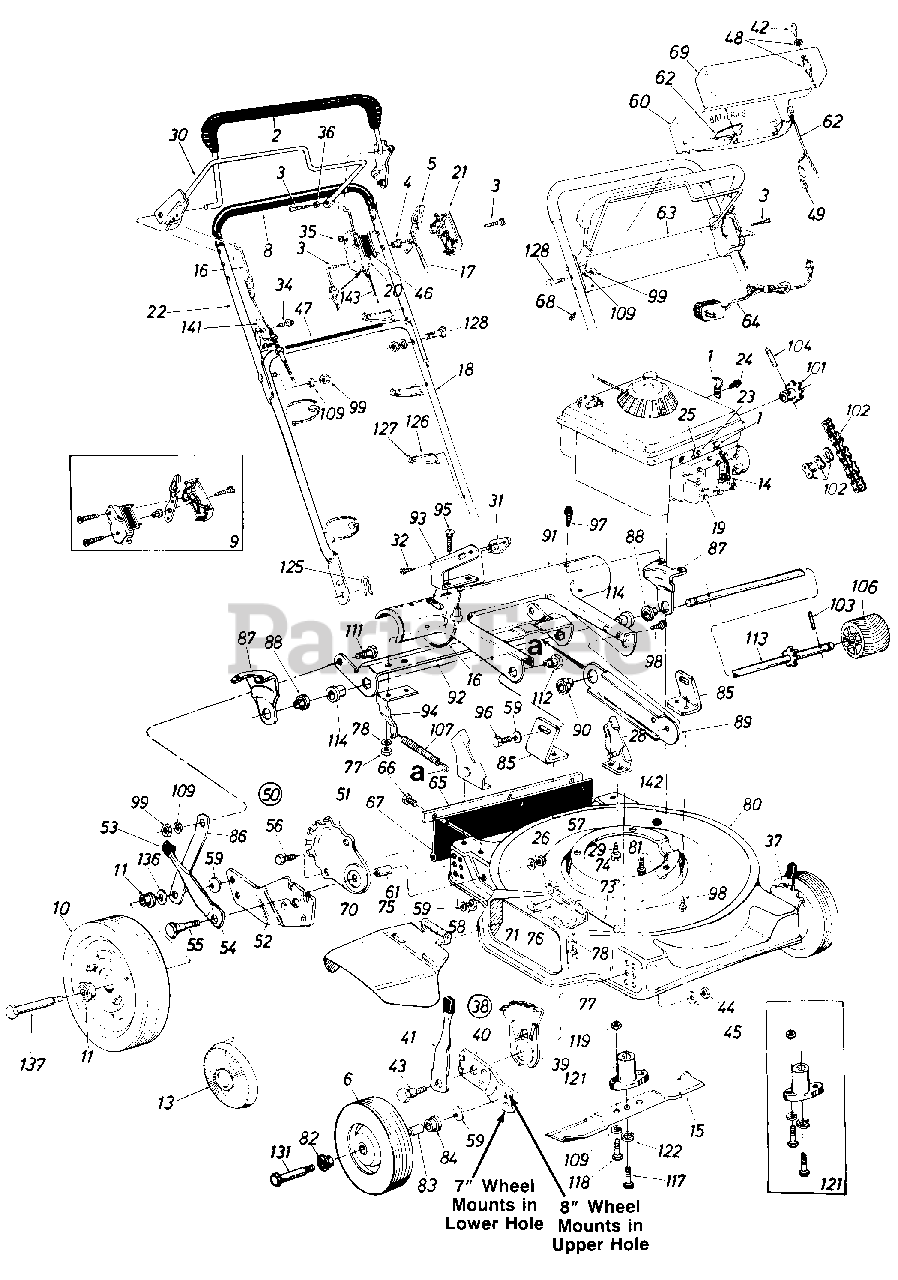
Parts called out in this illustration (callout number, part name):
1	Casing Clamp
2	Control Handle Ass'y.-L.H.
3	Truss Mach. Hi-B Tap Scr. #12 x 1.5"
4	Control Disc Pin
5	Throttle Control Lever
6	Front Wheel Ass'y. Comp.
9	Control Housing Comp.
10	Rear Wheel Ass'y. Comp.
11	Fl. Ball Brg. 1/2" I.D.
13	Hub Cap
14	Spark Plug Insulator
15	22" Blade
16	Clutch Cable w/Spring-33"
17	Throttle Wire-53"
18	Lower Handle (Chrome)
19	Engine
20	Clutch Panel Half
21	Control Panel Half
22	Upper Handle (Chrome)
23	Hex B-Tap Scr. #10 x .62"
24	Hex B-Tap Scr. #10 x .38"
25	Casing Clamp
26	Bell-Wash. 5/16" I.D.
28	Handle Brkt. Ass'y-L.H.
29	Hex B-Tap Scr. 5/16-18 x .5"
30	S.P. Bail Ass'y.
31	Barrel Cable Hold-Down R.H.
32	B-Tap Scr. #10 x .38 Lg.
34	Hex Wash. AB-Tap Scr. 5/16 x .75"
35	Spr-Wash. .206 I.D. x .448
36	Spacer .23 I.D. x .30 O.D.
37	Front Height Adj. Ass'y.-L.H.
38	Front Height Adj. Ass'y.-R.H.
39	Height Adj. Plate
40	Pivot Bar
41	Spring Lever Ass'y. w/Knob
42	Ignition Key
43	Shld. Bolt .50 Dia. x .430
44	Hex Nut 3/8-16 Thd.
45	Bell-Wash. .39 I.D. x 1.38 O.D
46	Control Label
47	Instruction Label
48	Ignition Switch
49	Plug
50	Rear Height Adj. Ass'y.-R.H.
51	Index Plate
52	Pivot Bar-R.H.
53	Spring Lever Knob
54	Spring Lever
55	Shld. Bolt .50 Dia. x .433
56	Hex Bolt 3/8-16 x .75
57	Hex Cent. L-Nut /16-18 Thd.
58	Hex Nut 3/8-16 Thd.*
59	Bell-Wash. .40 I.D. x .88 O.D.
60	Battery Pack
61	Spacer .383 I.D. x .503 O.D.
62	Wire Harness
63	Lower Battery Tray
64	Battery Charger
65	Retaining Strip
66	Hex AB-Tap Scr. 1/4 x .62
67	Rear Flap Ass'y.
68	Truss Mach. Hi-Riser Tap Scr. 1" Lg.
69	Battery Tray
70	Chute Deflector Ass'y.
71	Adapter Plate
73	Pivot Pin
74	Push Nut 1/4"
75	Torsion Spring
76	Hex Bolt 1/4-20 x .50 Lg.
77	Hex Nut 1/4-20 Thd.
78	L-Wash. 1/4 I.D.
80	22" Deck Ass'y.
81	Hex TT-Tap Scr. 3/8-16 x 1.0
82	Ball Bearing 3/8" I.D.
83	Spacer
84	Ball Bearing 1/2" I.D.
85	Pivot Brkt.
86	Link
87	Axle Brkt.
88	IFI. Ball Brg. 1/2" I.D.
89	Brg. Support
90	IFI. Ball Brg. 1/2" I.D.
91	Pinion-PivotCover
92	Drive Engagement Cam
93	Engagement Arm-L.H.
94	Spring Bracket
95	Carriage Bolt 1/4-20 x .62
96	Hex Bolt 3/8-16 x .50 Lg.*
97	Hex AB-Tap Scr. 1/4 x .62
98	Hex AB-Tap 1/4 x .62"
99	Hex Nut 5/16-18 Thd.
101	1OT Sprocket Ass'y.
102	#48 Chain 1/2" Pitch 50 Links
103	Spring Pin Spir. 3/16 Dia. x 1 25
104	Spring Pin Spir. 3/16 Dia. x 1.0
106	Drive Pinion
107	Extension Spring 4.25 Lg.
109	L-Wash. 5/16 I.D.
111	Shld. Bolt .437 Dia. x .162
112	Shld. Nut .625 Dia. x .165
113	Pinion Shaft w/7T Sprocket
114	Fl. Ball Brg. .501 I.D.
117	Hex Bolt 3/8-24 x 2.25
118	Hex Bolt 5/16-24 x 1.0-Spec.
119	Hex Nut 5/16-24 Thd.
121	Blade Adapter Kit
122	L-Wash. 3/8 I.D.-H.D.
125	Intern. Cot. Pin 5/16 Dia.
126	Cable Tie
127	Cable Anchor
128	Curved Carriage Bolt 5/16-18 x 1.38" Lg.
131	Front Axle Bolt
136	Fl-Wash. .531 I.D. x .93 O.D.
137	Rear Axle Bolt
141	Cable Brkt.
142	Plastic Plug
143	Control Cable-39" (Green)
